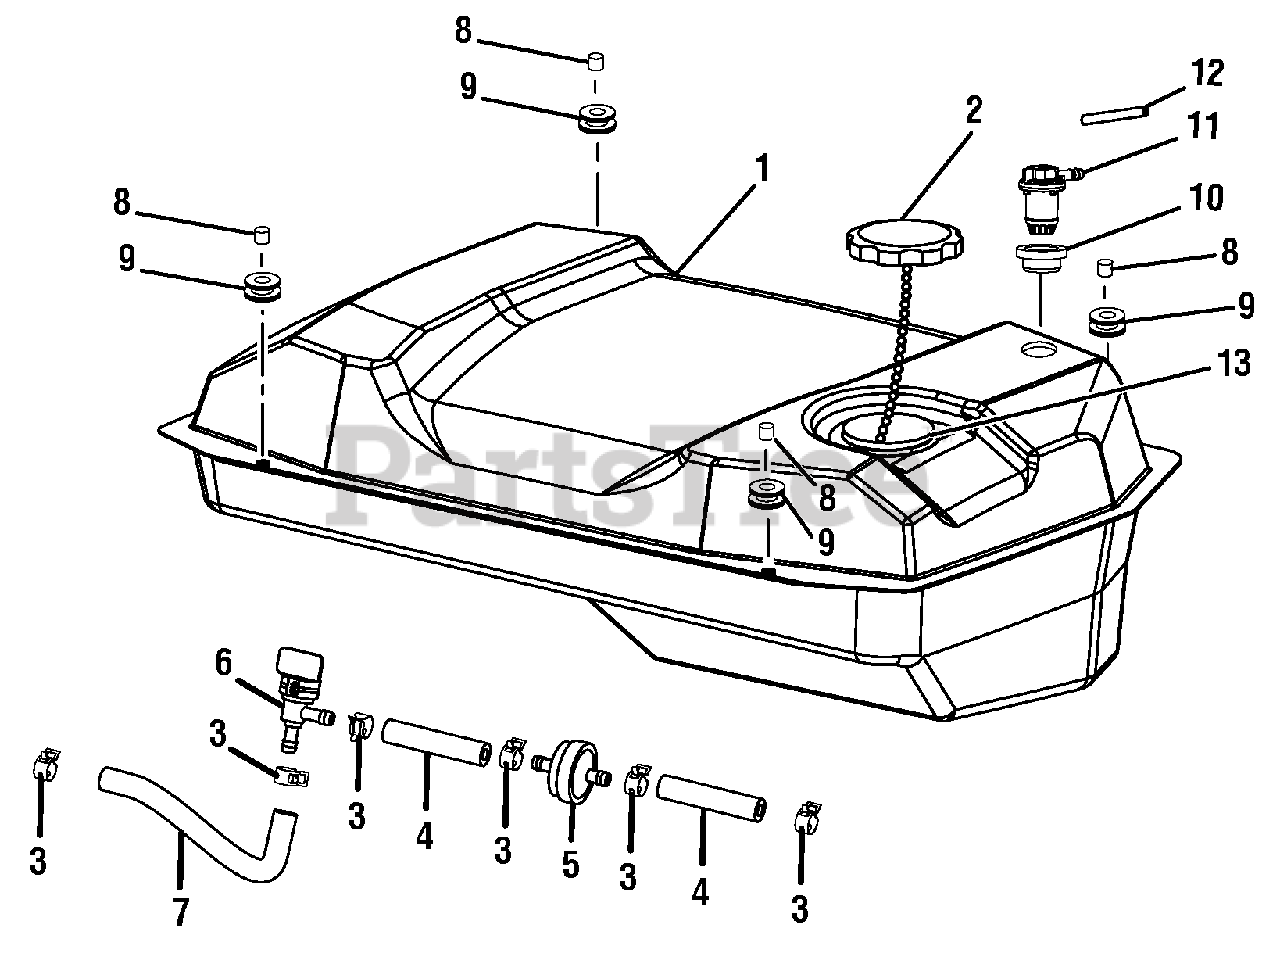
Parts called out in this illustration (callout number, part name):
1	FUEL TANK
2	FUEL TANK CAP
3	FUEL LINE CLAMP (1/2 IN.)
4	FUEL LINE (105 MM)
5	FUEL FILTER
6	FUEL SHUT OFF VALVE
7	FUEL LINE (208MM)
8	SPACER (FUEL TANK ISOLATOR)
9	ISOLATOR (FUEL TANK)
10	BUSHING
11	ROLLOVER VALVE
12	ROLLOVER VENT
13	RING CLIP
